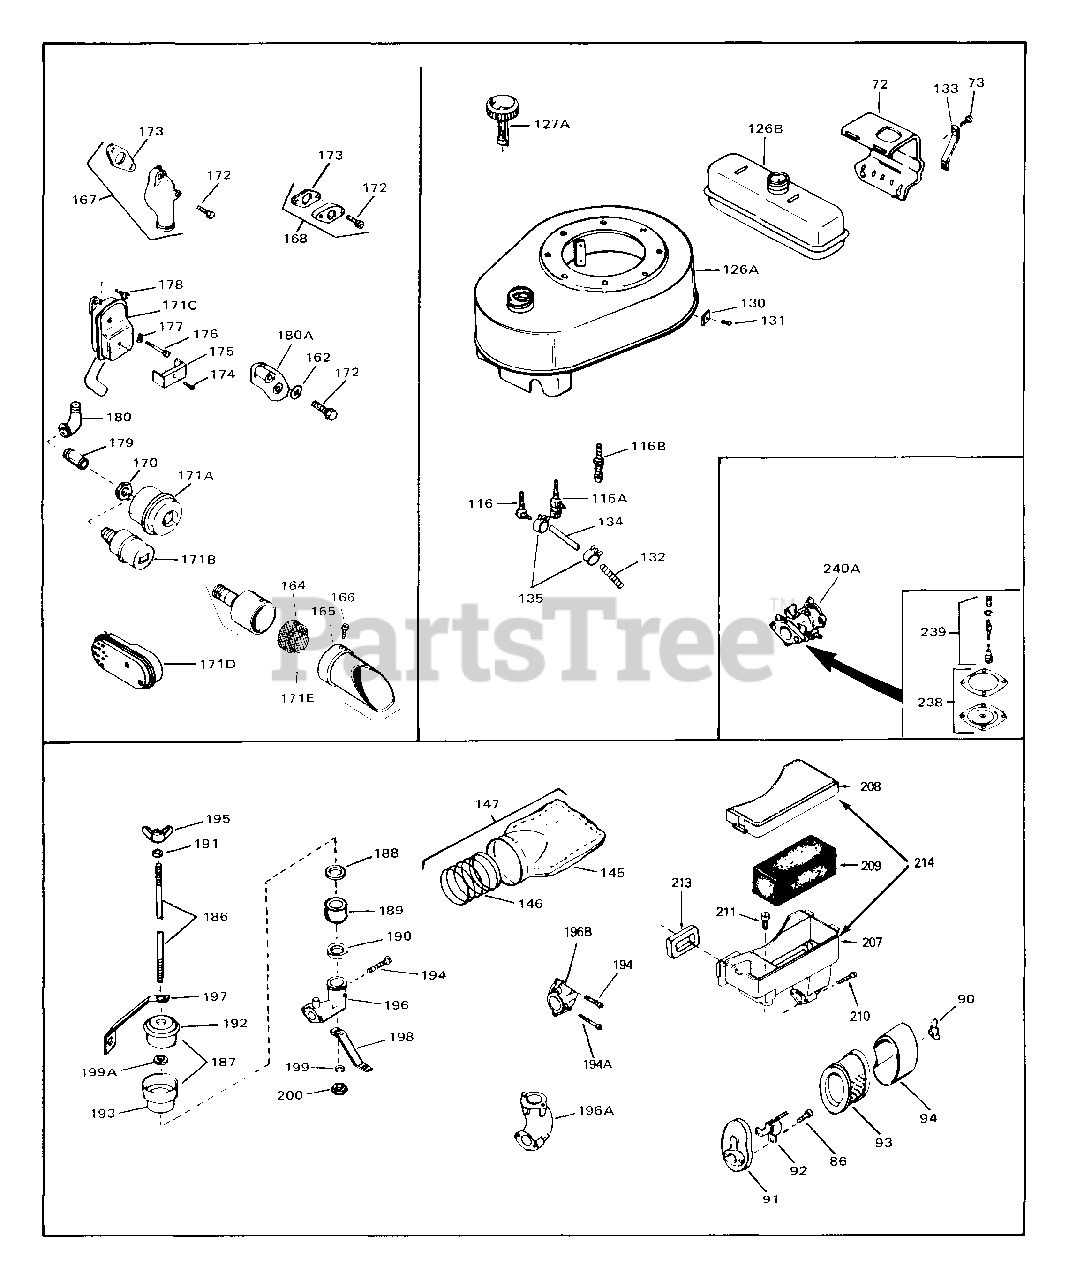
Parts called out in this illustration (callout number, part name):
72	Strap, Fuel tank
73	Screw, Hex hd. Sems, 5/16-18 x 7/8
86	Screw
116	Strainer & Elbow
116A	Strainer & Shut-off
116B	Strainer & Fitting
130	Plate, Securing
131	Screw
132	Spring, Fuel line
133	Brace, Fuel tank
134	Line, Fuel (Braided 8.25")
134	Line, Fuel (Braided 16")
134	Line, Fuel (Braided 32")
134	Line, Fuel (Braided 48")
135	Clamp, Fuel line
145	Bag, Pre-cleaner
146	Spring, Pre-cleaner bag
147	Kit, Pre-cleaner
162	Lockwasher
164	Screen, Muffler
165	Cover & Tube, Muffler
167	Muffler Adapter Kit
168	Muffler Adapter Kit
170	Nut, Conduit (1/8" thick)
170	Nut, Conduit (1/4" thick)
171E	Muffler
172	Screw, Hex flange hd., 5/16-18 x 1-1/ 2
172	Screw, Hex flange hd., 5/16-18 x 2-1/ 4
172	Screw, Hex hd., 5/16-18 x 2-3/4
172	Screw, Hex flange hd., 5/16-18 x 2-1/ 2
173	Gasket, Exhaust
179	Nipple, Exhaust pipe (2-1/2")
179	Nipple, Exhaust pipe (2")
179	Nipple, Exhaust pipe (1-3/8")
180	Elbow, Exhaust (90(deg))
180	Elbow, Exhaust (45(deg))
